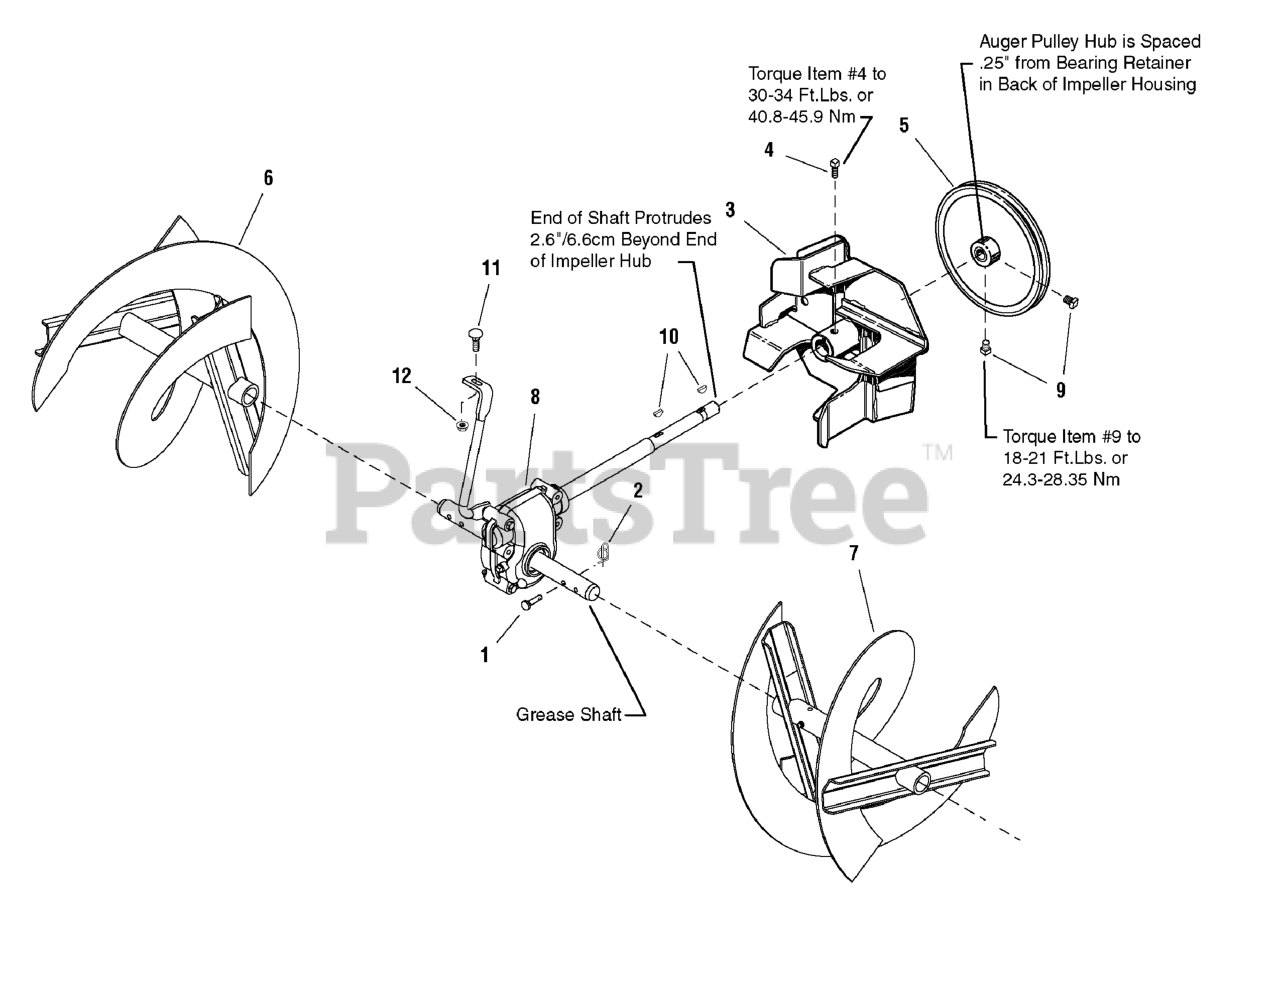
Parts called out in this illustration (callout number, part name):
1	PIN, Shear
2	COTTER PIN, 1/4" Self Locking
3	IMPELLER ASSEMBLY
4	SCREW, Set Square Head Cup Point, 3/8-16 x 1/2 G8
5	PULLEY, 8.40 OD .752ID .720WD W/Hub
6	AUGER ASSEMBLY, 24" & 26" R.H.
6	AUGER ASSEMBLY, 28" & 30" R.H.
6	AUGER ASSEMBLY, 32" R.H.
7	AUGER ASSEMBLY, 24" & 26" L.H.
7	AUGER ASSEMBLY, 28" & 30" L.H.
7	AUGER ASSEMBLY, 32" L.H.
8	GEAR BOX ASSEMBLY
9	SCREW, Set Square Head Cup Point, 5/16-18 x 1/2 G8
10	KEY, Woodruff
11	CARRIAGE BOLT, 5/16-18 x 3/4 G5
12	NUT, Hex Flange Whiz Lock, 5/16-18
15	TUBE
